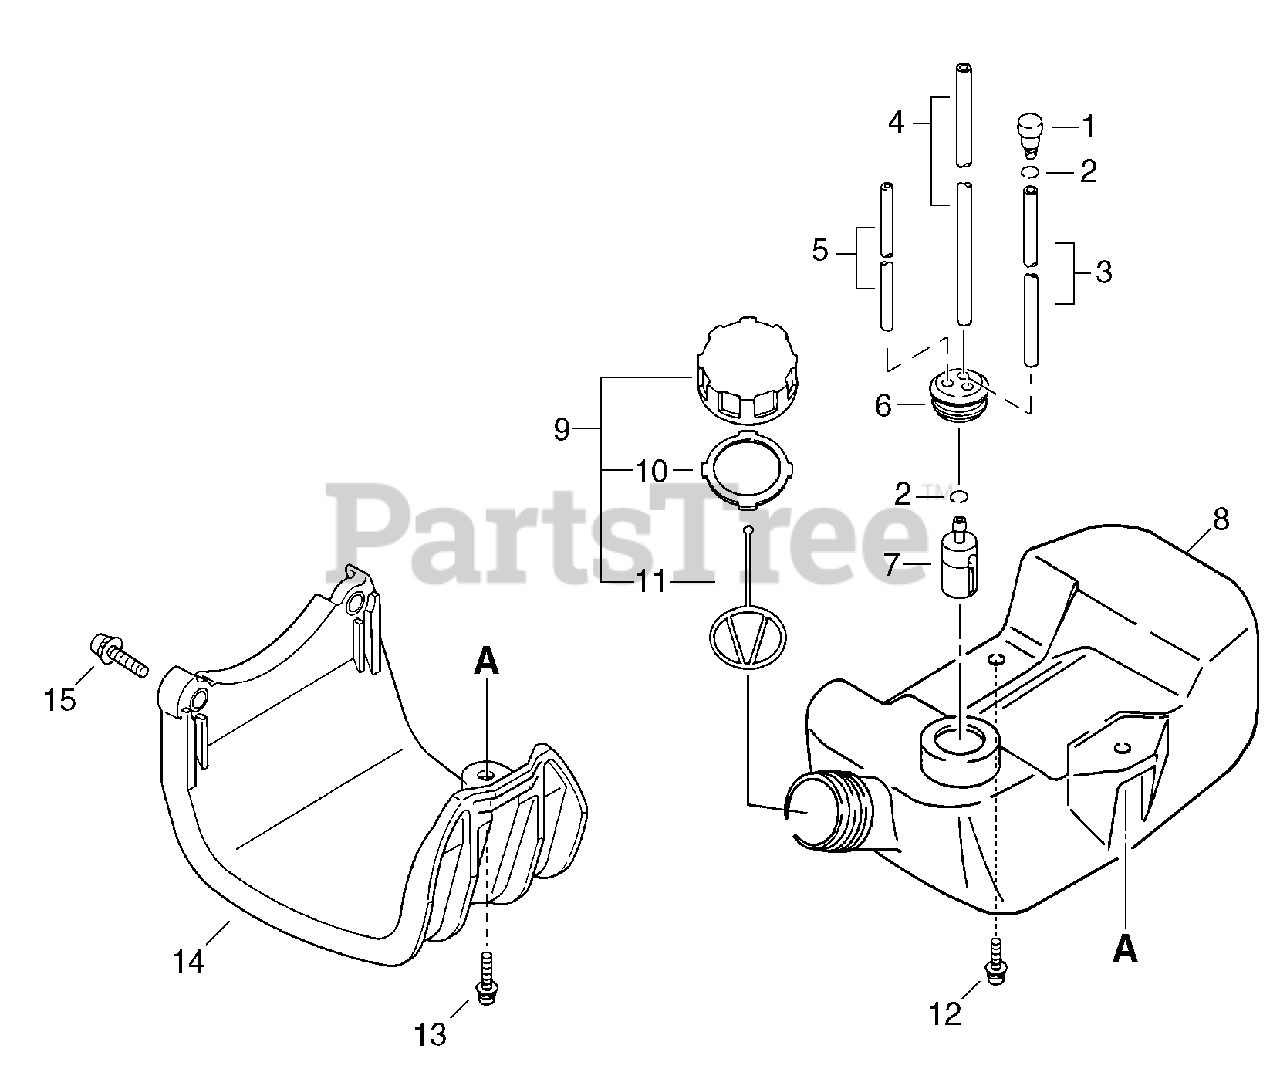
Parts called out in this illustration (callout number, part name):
1	VENT ASSY
2	CLIP Ø6.5 MM
3	PIPE, FUEL 3×6×100
4	PIPE, FUEL 3×6×170
5	PIPE, FUEL 3×6×60 CLEAR
6	GROMMET, FUEL
7	FILTER, FUEL
8	TANK, FUEL
9	CAP ASSY, FUEL
10	GASKET, FUEL CAP
11	CONNECTOR, CAP L= 100 MM
12	SCREW 5×16
13	SCREW 5×20
14	GUARD, FUEL TANK
15	BOLT 5×22
